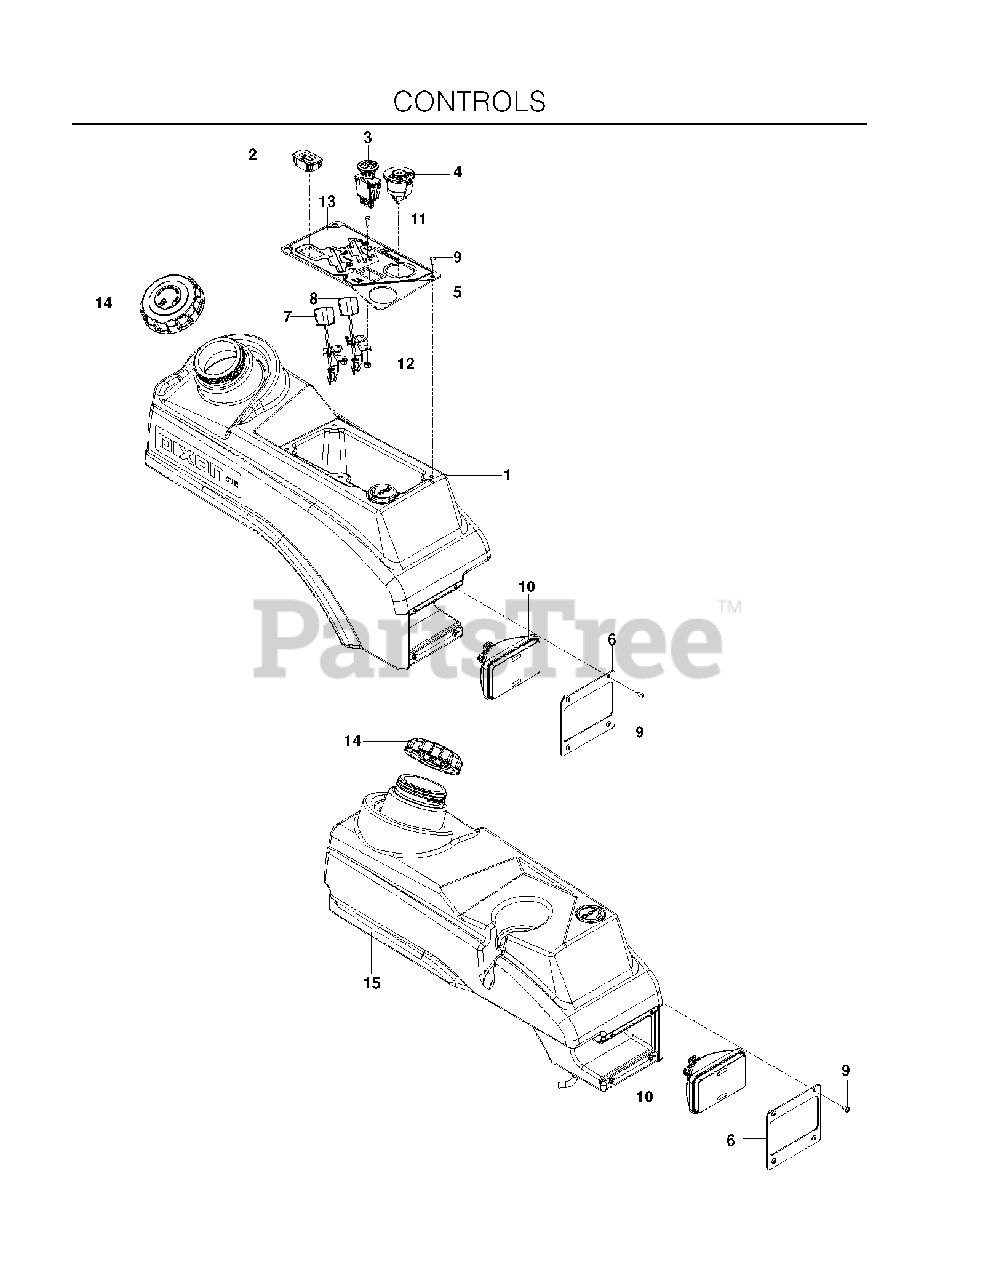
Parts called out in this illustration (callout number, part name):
1	TANK, FUEL, RT
2	HOUR METER
3	SWITCH, PTO 10 AMP
4	IGNITION SWITCH
5	CONTROL PANEL
6	PLATE LIGHT
7	CABLE THROTTLE
8	CHOKE CABLE
9	SCR #10-24 X 3/8 SKT HD BLK OX
11	HCS #10-24 X 1/2
12	NUT 10-24 NYLOC
13	DECAL, CONTROL
14	FUEL CAP, GENERIC
15	TANK, FUEL, LT
